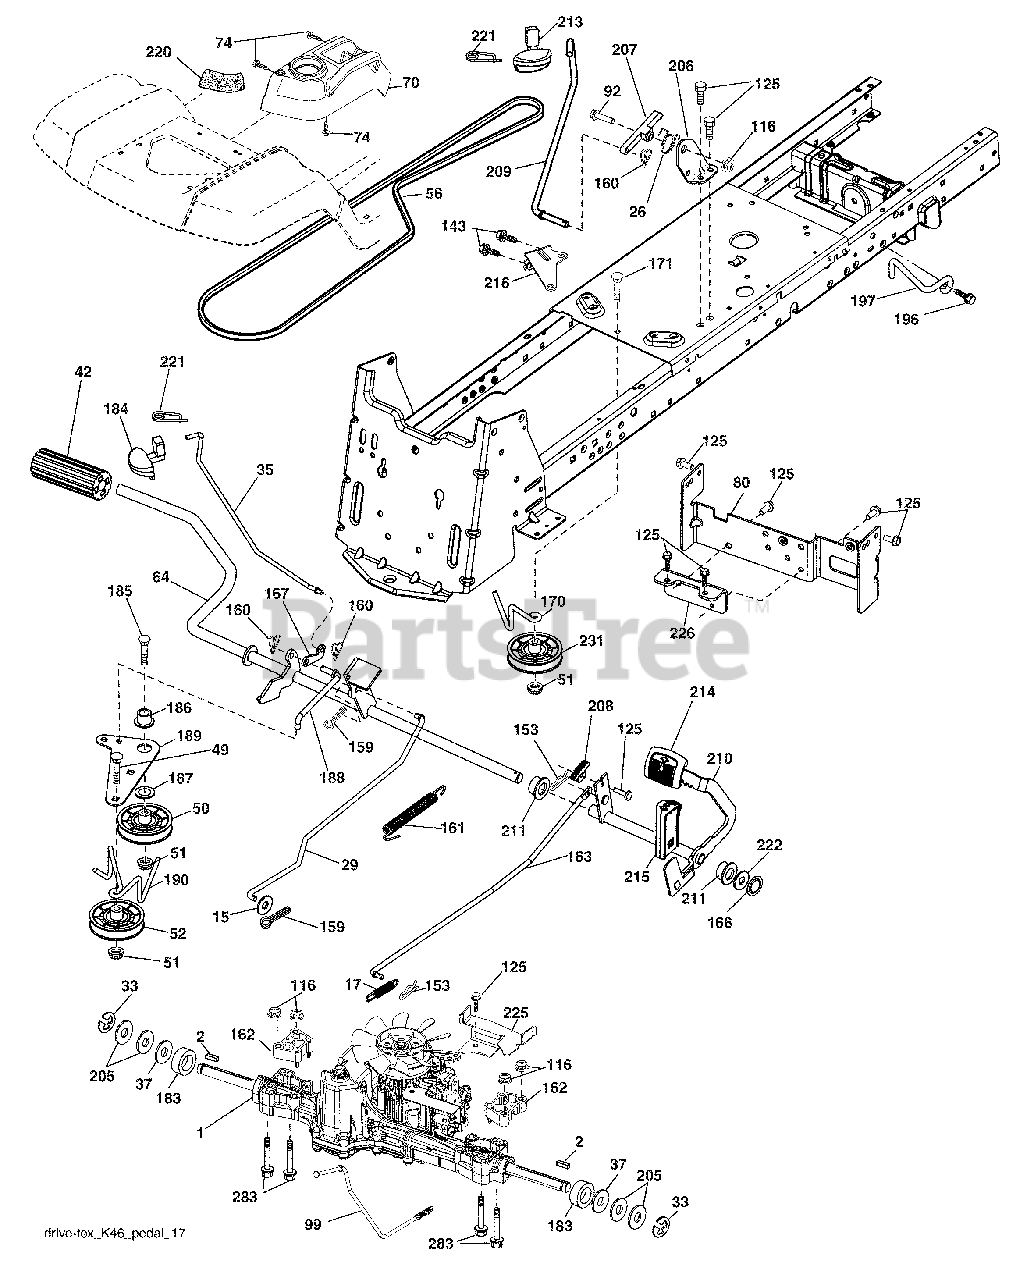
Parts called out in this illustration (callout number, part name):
1	Transaxle, TUFFTORQ K46 BT
2	Key 1/4 x 2.5
15	Washer 13/32 x 13/16 x 16 Ga.
17	Spring, Brake
26	Spring Return Cruise
29	Rod, Brake
35	Rod, Brake, Park
37	Washer Harden
42	Cover, Foot Pedal
50	Pulley Idler Flat
51	Lock Nut 3/8-16
52	Idler V-Groove 910" Offset
56	V-Belt, Drive
64	Shaft Asm. Pedal Brake Control
70	Console Asm.
74	Screw 1/4 x 1/2
80	Strap Torque
92	Bolt Fin Hex 5/16-18 unc x 1.25
99	Rod Spring Bypass
116	Nut Lock Hex Flange 5/16-18
125	Screw 5/16-18 x 3/4
143	Screw Thdrol 5/16-18 x 1/2
153	Retainer Spring
159	Pin Cotter 1/8 x 3/4
160	Retainer Clip
161	Spring, Return, Clutch
162	Spacer Transaxle
163	Rod Pedal Control
166	Nut Push .625
167	Latch Brake Parking
170	Keeper Belt Centerspan
171	Bolt RDHD 3/8-16 unc x 2-3/4 Gr. 5
183	Spacer Split
184	Handle Parking Brake
185	Bolt Rdhd Sqnk 3/8-16 x 2-1/2
186	Spacer Retainer
187	Washer
188	Link Clutch Ground Drive
189	Bellcrank Ground Drive
190	Keeper Bellcrank Ground Drive
196	Screw 3/8-16 x 1
197	Link Clutch Anti-Rotation
206	Bracket Mount Latch Cruise
207	Latch Control Cruise
208	Gear Sector Control Cruise
209	Rod Control Cruise
210	Rocker Asm. Pedal Control
211	Bearing Nylon
213	Knob Control Cruise
214	Pedal Forward
215	Pedal Reverse
216	Bracket Pulley Idler
220	Reflector RH
221	Retainer Spring Clip Handle
222	Washer 21/32 x 1-1/4 x 10 Ga.
225	Keeper Belt Trans.
226	Bracket Mount Torque
231	Idler V-Groove
283	Bolt Hex WSHRHD 5/16-18 x 4.25 Gr. 5
